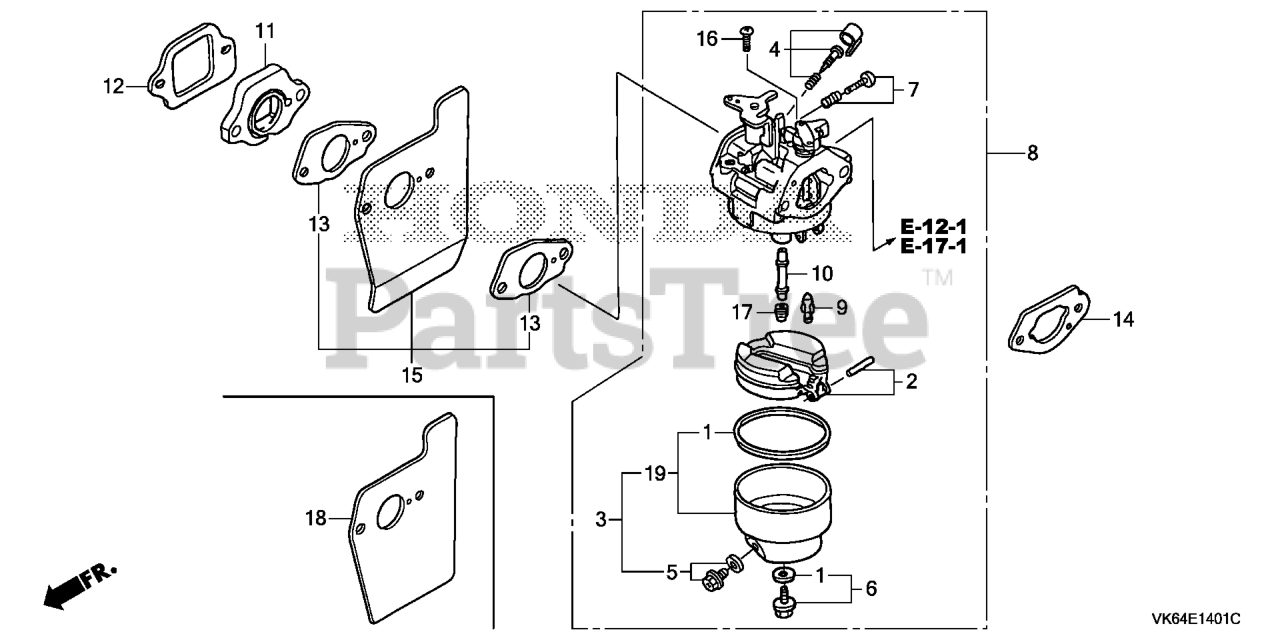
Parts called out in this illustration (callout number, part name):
1	GASKET SET
2	FLOAT SET
3	CHAMBER SET, FLOAT
4	SCREW SET (CARBURETOR NO.)
5	SCREW SET, DRAIN (Honda Code 1672187). (CARBURETOR NO.)
6	SCREW SET B
6	SCREW SET
7	SCREW SET (THROTTLE STOP) (CARBURETOR NO.)
8	CARBURETOR ASSY. (BB65F A)
8	CARBURETOR ASSY. (BB65F B)
8	CARBURETOR (BB65W A)
9	VALVE, FLOAT (Honda Code 7934714). (CARBURETOR NO.)
10	NOZZLE, MAIN
11	INSULATOR, CARBURETOR
12	GASKET, INSULATOR
13	GASKET, CARBURETOR
14	GASKET, CARBURETOR (Honda Code 5580253). (CHOKE SIDE)
15	GUIDE, AIR
16	SCREW, PAN (5X6)
17	JET, MAIN (#60) (Honda Code 0635474). (CARBURETOR NO.)
17	JET, MAIN (#65) Use up to Engine SN BB30A D.
17	JET, MAIN (#62) (Honda Code 0635482). (CARBURETOR NO.)
17	JET, MAIN (#68) Use up to Engine SN BB30A D.
18	GUIDE, AIR
19	CHAMBER SET, FLOAT (CARBURETOR NO.)
